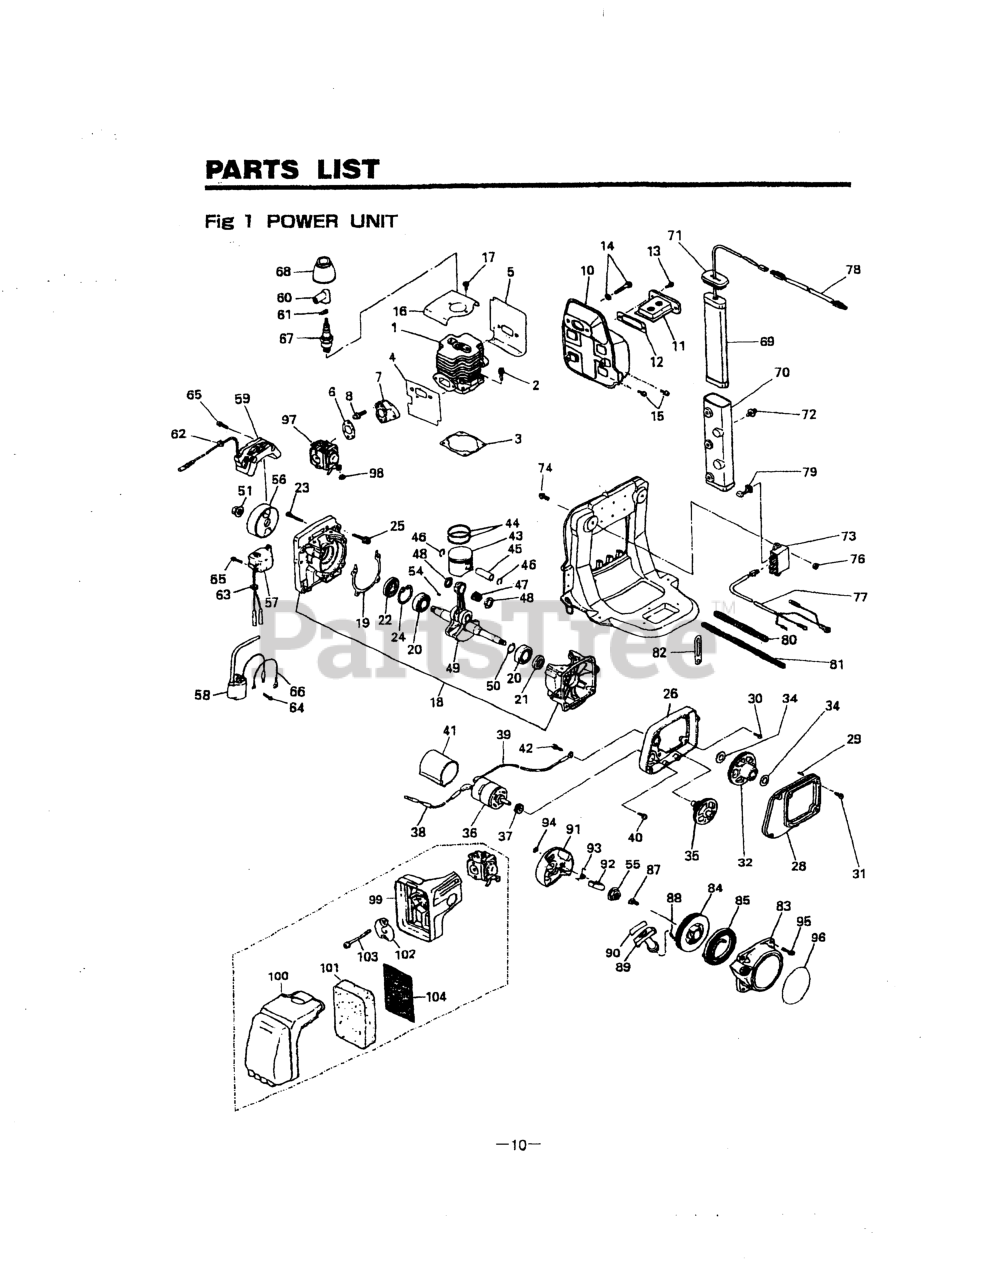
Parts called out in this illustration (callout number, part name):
1	CYLINDER (RPLS -12111)
2	BOLT, M5 x 22
7	INSULATOR (RPLS-14112)
10	MUFFLER (RPLS -15101)
11	ARRESTER
13	SCREW, M4 x 10
18	CRANKCASE COMP.
21	SEAL, OIL - STARTER SIDE
23	BOLT, M5 X 30
24	RING, SNAP, M35 X 1.5
25	BOLT (RPLS -21510)
26	GEARCASE COMP.
28	COVER COMP.
29	PIN, DOWEL
31	SCREW, M4 X 16
35	GEAR (B) (RPLS-23201)
36	MOTOR
37	GEAR (RPLS -24150)
38	CORD (YELLOW)
39	CORD (BLACK)
40	SCREW, M4 x 10
41	COVER, MOTOR
42	BOLT, M5 X 12
44	RING, PISTON (RPLS -41210)
46	RING, SNAP
47	BEARING
48	WASHER (RPLS 1491-41510)
50	SHIM (REPLACES 848-870-G000)
51	NUT, M10
54	KEY
58	COIL, IGNITION
59	COIL, GENERATOR
61	SPRING
63	GROMMET
64	SCREW, M4 x 16
65	SCREW (REPLACES -30414)
66	CABLE COMPLETE
68	CAP (NO LONGER AVAILABLE)
69	BATTERY
72	CLIP
73	RELAY
74	BOLT
76	NUT, M5 X 4
77	CORD ASSEMBLY
78	CORD ASSEMBLY
83	RECOIL ASSEMBLY
84	REEL
85	SPRING, SPIRAL
87	SCREW (RPLS -75150)
89	KNOB
91	PULLEY ASSEMBLY
92	RATCHET
93	SPRING, RETURN
94	E-RING
95	SCREW, M5X20 (RPLS.1400-75510)
96	LABEL, RECOIL
98	CAP, CABLE END
102	PLATE, SHUT
103	SCREW, M5 X 55
